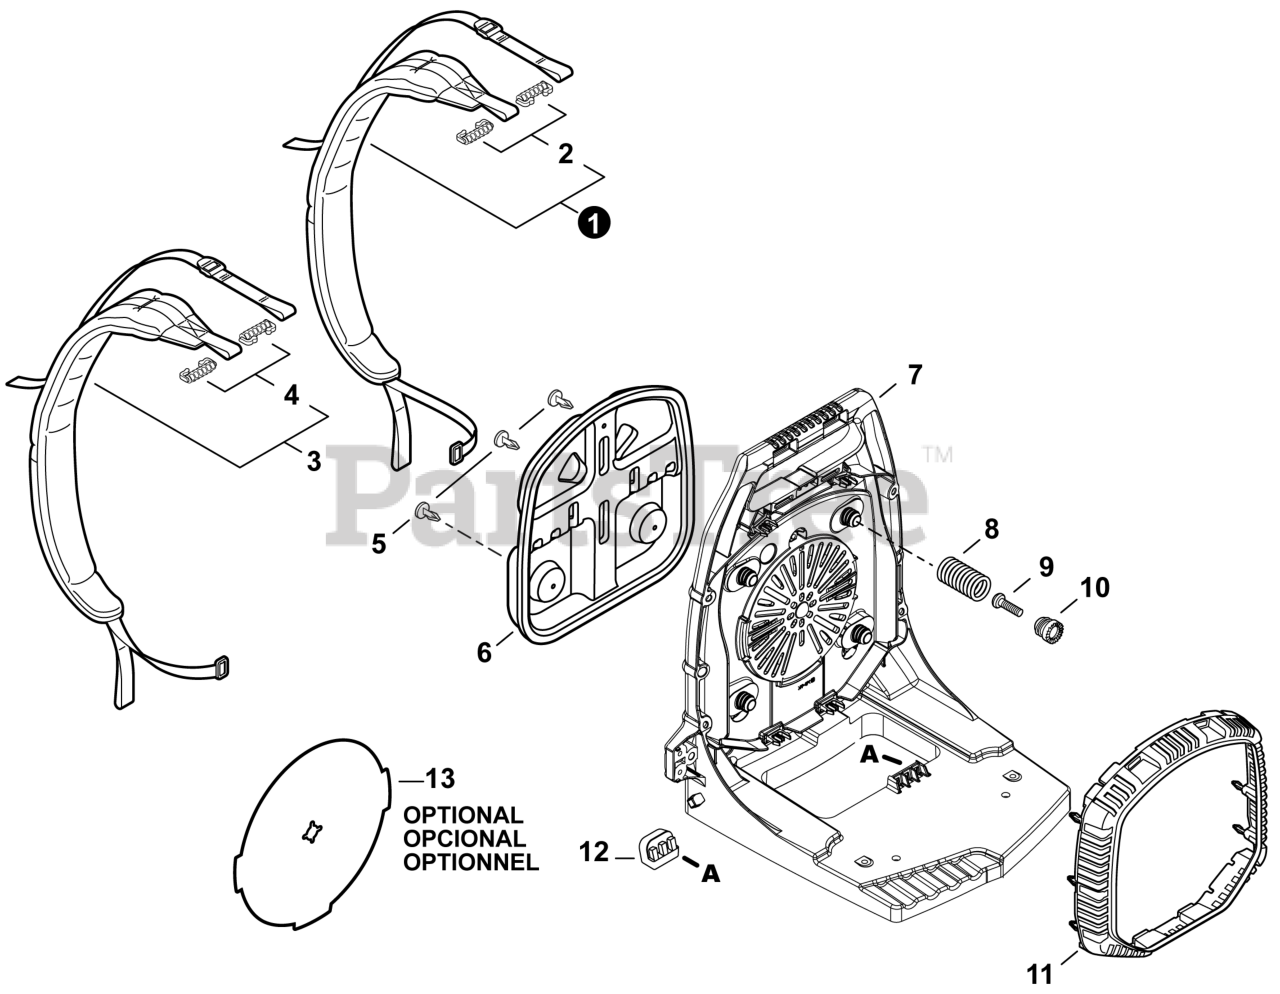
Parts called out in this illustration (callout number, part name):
1	HARNESS ASSY, RIGHT
2	CLIP
3	HARNESS ASSY, LEFT
4	CLIP
6	CUSHION, BACKPACK
7	FRAME, BACKPACK
8	SPRING, COMPRESSION
9	BOLT, TORX 5x20
10	HOLDER, SPRING
11	GUARD, DEBRIS
12	CUSHION
13	INSERT, COLD WEATHER
